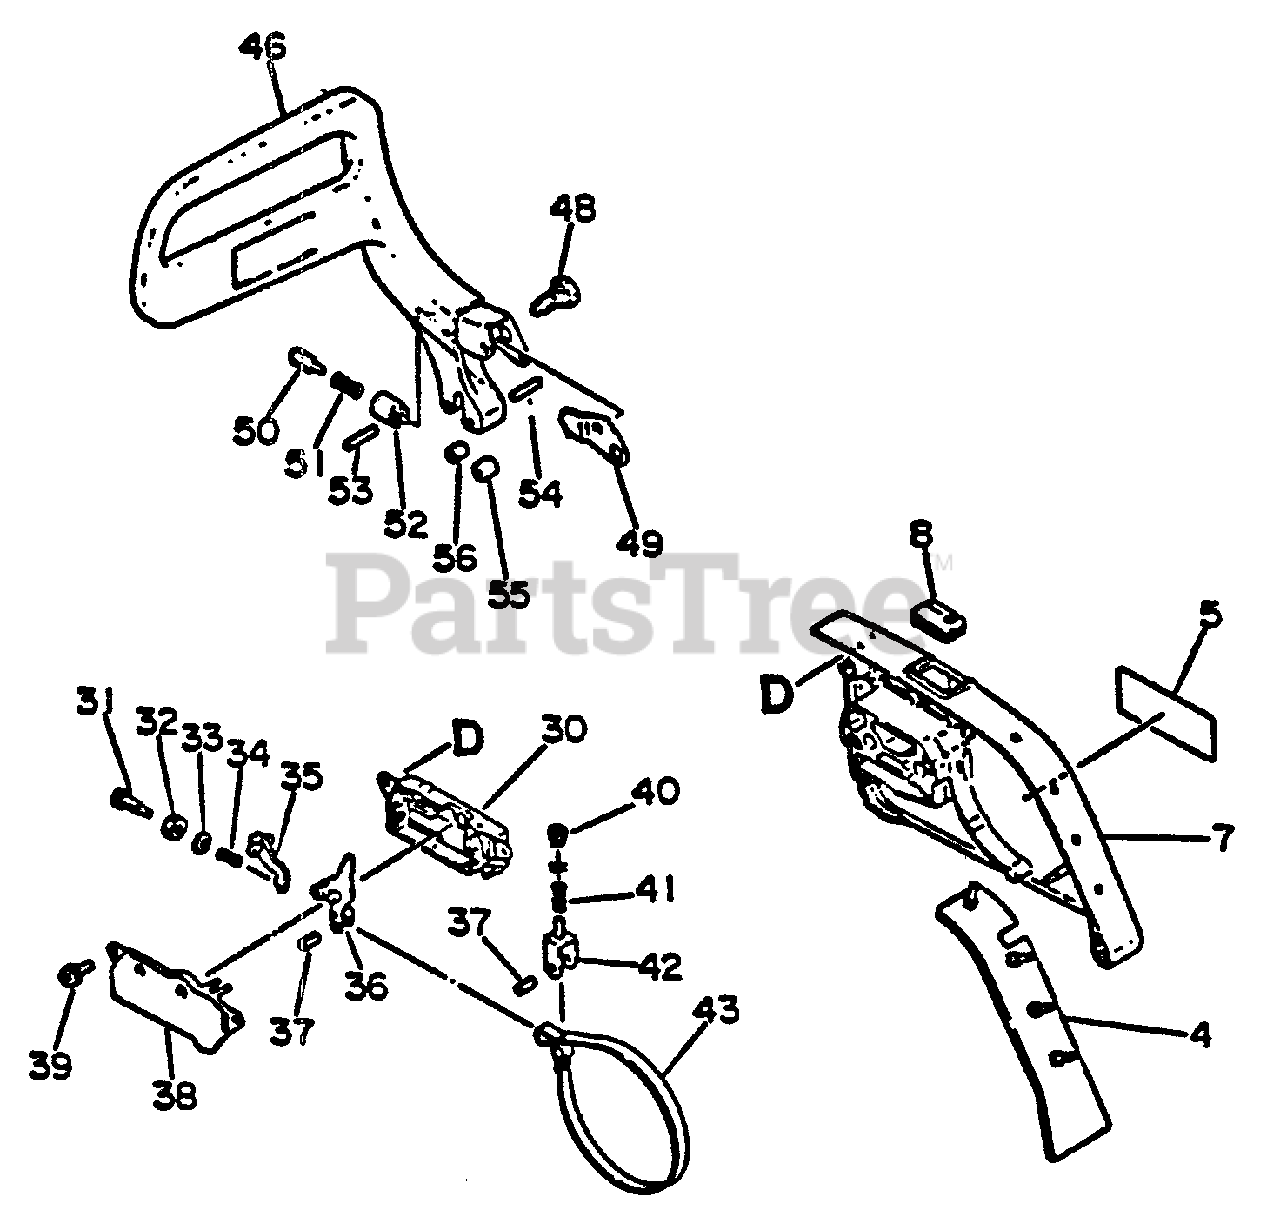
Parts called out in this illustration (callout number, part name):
4	PROTECTOR
5	LABEL - ECHO
7	GUARD, SPROCKET
8	CHAIN BRAKE ASSY
30	COVER, BRAKE
34	SPRING ,BRAKE
35	STOPPER, BRAKE
36	LEVER, BRAKE
37	PIN, SPRING
39	SCREW - 4×10
42	ADJUSTER, BRAKE BAND
43	BAND, BRAKE
46	BRAKE LEVER ASSY
53	PIN 2×20
54	PIN 3×18
56	SPACER
